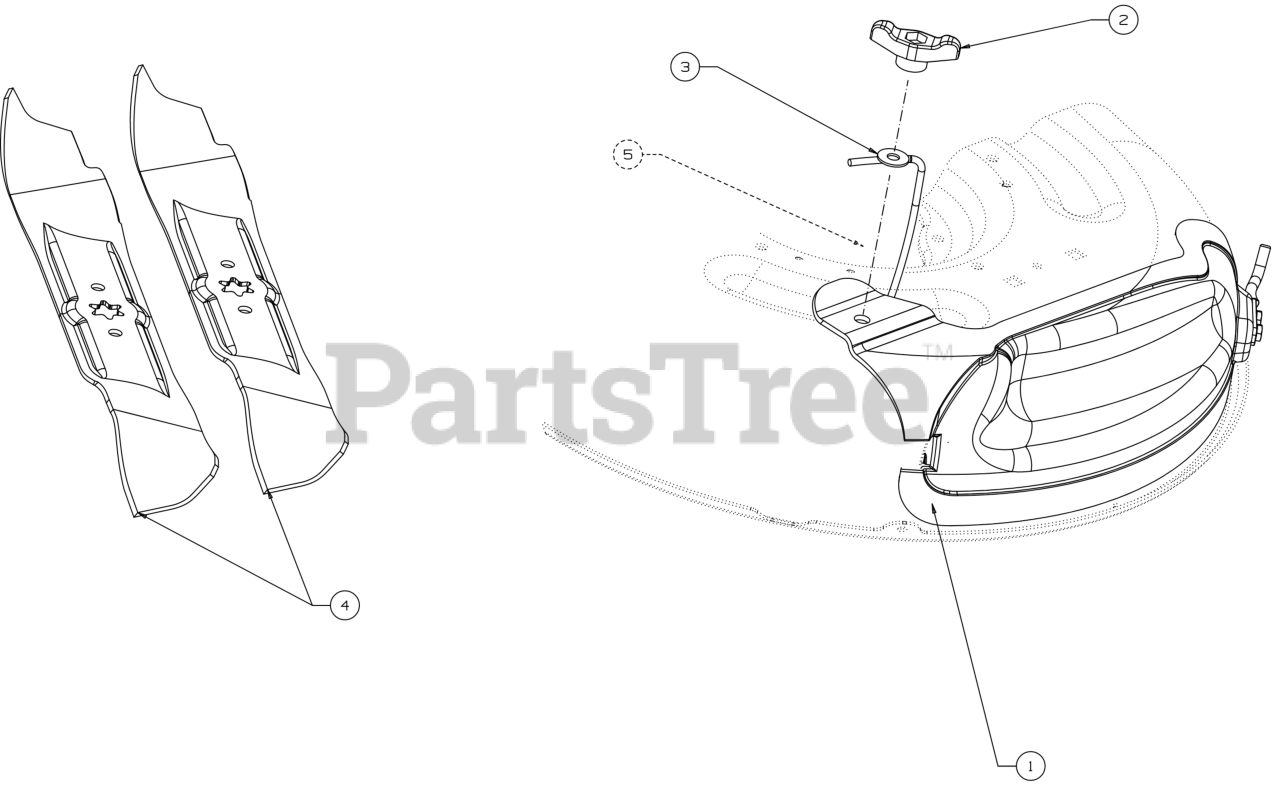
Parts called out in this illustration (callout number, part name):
1	MULCH PLUG ASSEMBLY
2	WING KNOB 5/16-18
3	FLAT WASHER
4	21.23" BLADE (MULCH)
4	Cub Cadet 42" RZT BLADE SET
4	Genuine Factory Parts 42" BLADE SET(STD)
4	21.23" BLADE (2N1) (XTREME)
4	42" 6 PT STAR LOW LIFT/SAND BLADE
5	MULCH PLUG SUPPORT ROD
